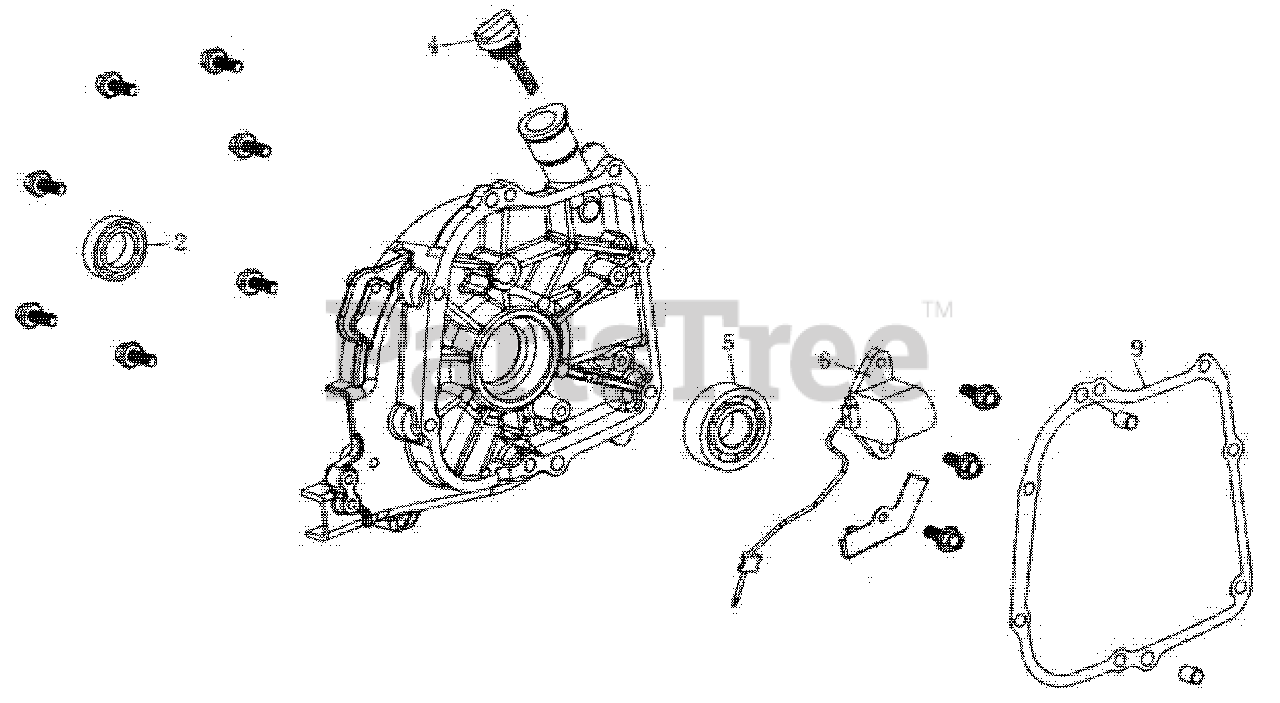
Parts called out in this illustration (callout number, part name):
2	OIL SEAL
4	CAP ASSY
5	BALL BEARING
6	OIL LEVEL SWITCH
9	PACKING , CASE COVER
